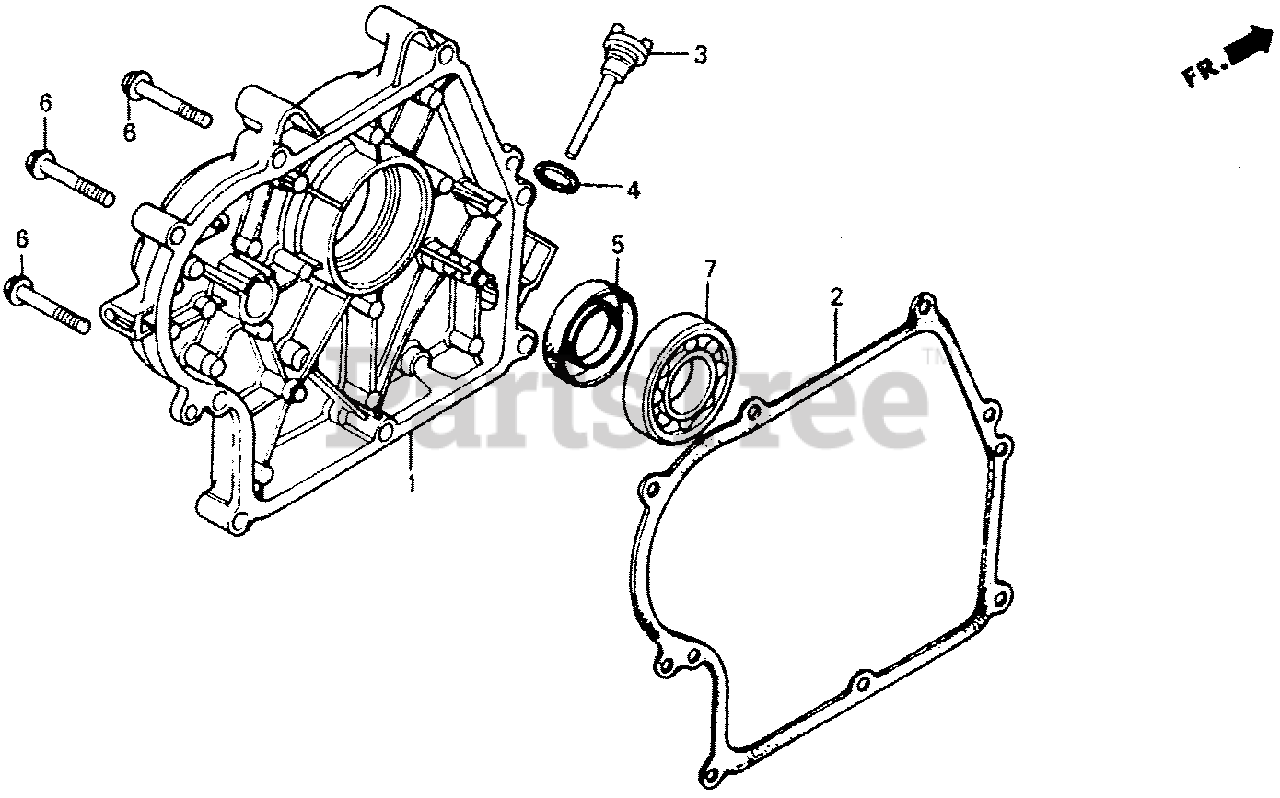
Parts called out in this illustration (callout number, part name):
1	COVER, CRANKCASE
2	GASKET, CASE COVER
3	CAP, OIL FILLER
4	GASKET, OIL FILLER CAP
5	OIL SEAL (30X46X8)
6	BOLT, FLANGE (8X40)
7	BEARING, RADIAL BALL (6206)
